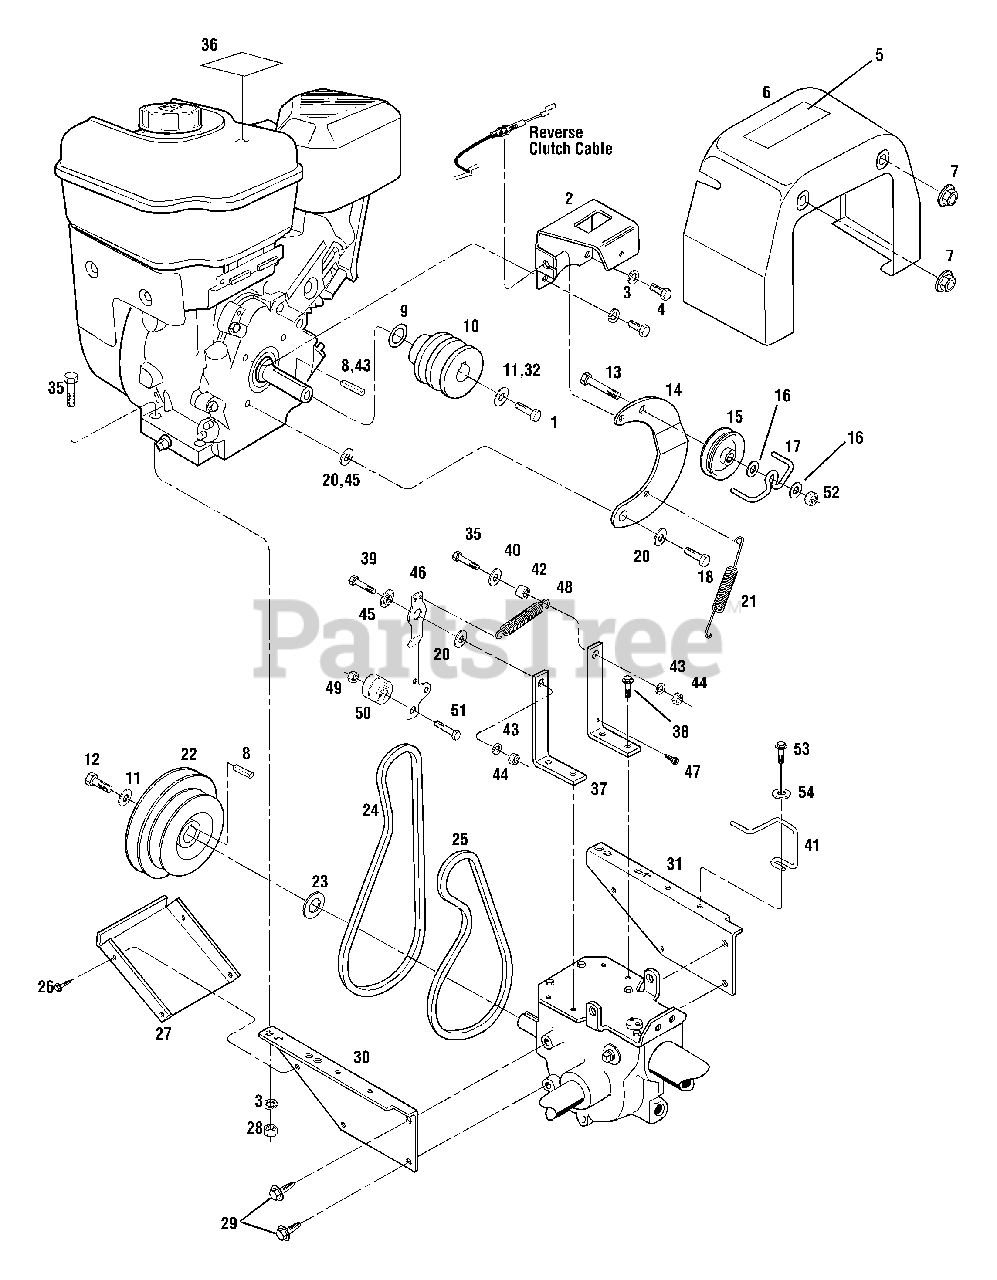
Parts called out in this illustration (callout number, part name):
1	Screw, 3/8-24 x 1.75
2	Bracket, Clutch Cable
3	Lockwasher-5/16
4	Hex Hd. Screw, 5/16-24 x 1/2
5	Decal, Hot Surfaces/Belt Warning
6	Cover
7	Flange Lock Nut, 5/16-18
8	Key, 3/16 x 1-1/2
9	Shim
10	Pulley, Engine Drive
11	Belleville Washer
12	Hex Hd. Screw, 5/16-24 x 1-1/8
13	Hex Hd. Screw, 5/16-18 x 2
14	Reverse Idler Arm
15	Pulley, Reverse Idler
16	Flat Washer, 5/16
17	Belt Guide, Wire Formed
18	Hex Head Screw, 5/16-24 x 1
19	Washer, Shoulder
20	Washer, Flat, 1-1/8
21	Spring, Reverse Return
22	Transmission Pulley
23	Support Washer
24	Reverse Clutch Belt
25	Forward Clutch Belt
26	Self-tapping Screw, #10-32 x 1/2
27	Guard, Belts/Pulleys
28	Hex Flange Nut, 5/16-18
29	Hex Flange Screw, 5/16-18 x 3/4
30	Engine Support Bracket, left side
31	Engine Support Bracket, right side
32	Bell Washer
35	Hex Hd. Screw, 5/16-18 x 2-1/4
36	Decal, Stabilization
37	Mounting Bar
38	Hex Flange Screw, 5/16-18 x .75
39	Hex Hd. Screw, 5/16-18 x 1-1/2
40	Flat Washer, 5/16"
41	Belt Guide, Pony
42	Pivot Bushing
43	Key, .188 x 1.75
44	Hex Nut, 5/16-18
45	Washer, Shoulder
46	Idler Arm, Forward Tiller Direction
47	Screw, self tapping, #10-24
48	Spring
49	Hex Locknut, 5/16-18
50	Idler Pulley, Forward
51	Screw, 3/8-16 x 1-3/4
52	Hex Lock Nut, 5/16-18
53	Screw, 1/4-20 x 3/4
54	Flat Washer-1/4
